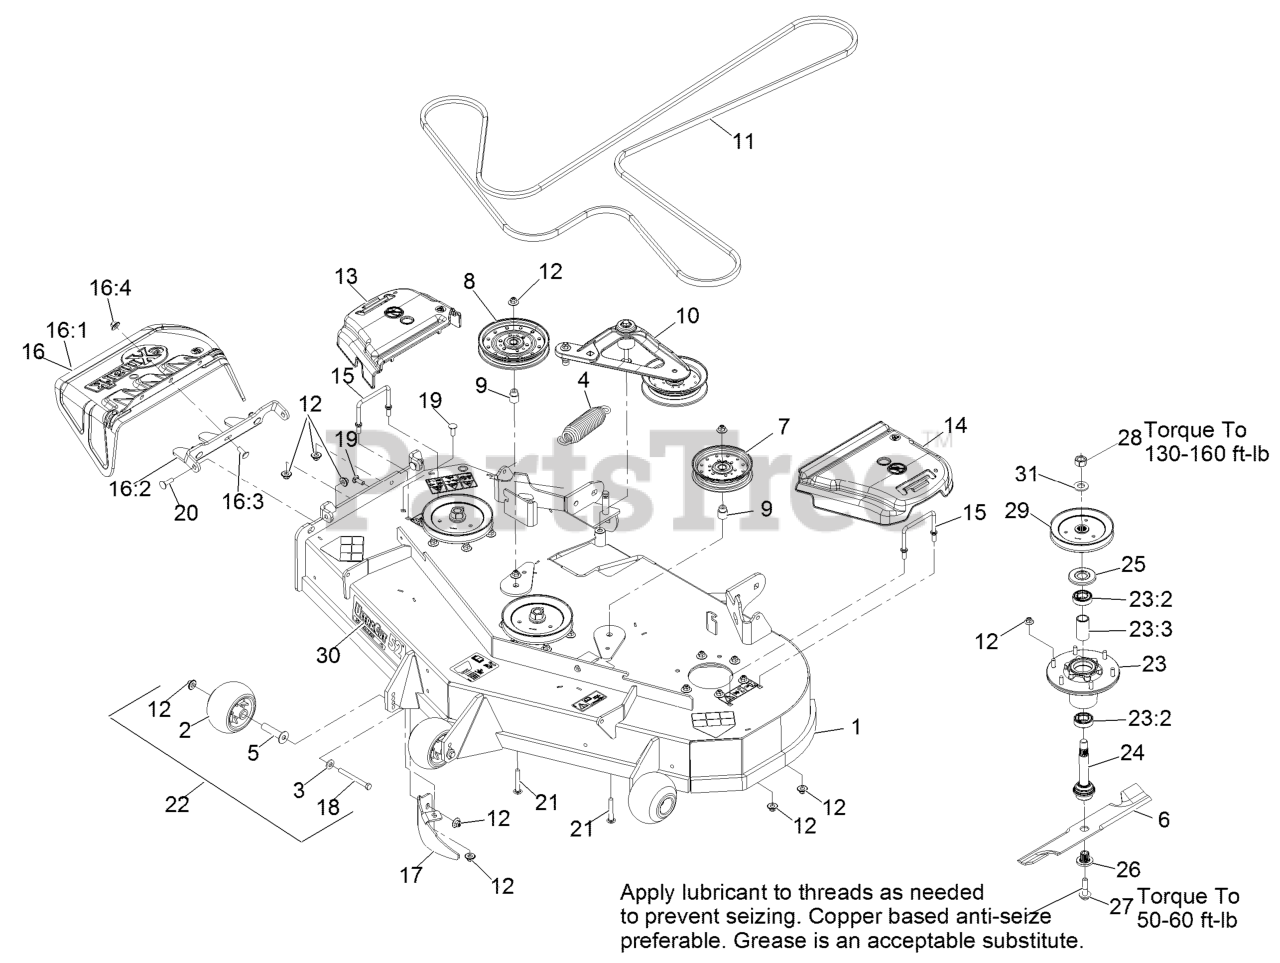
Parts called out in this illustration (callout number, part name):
1	ASM,DECK W/ DECALS 52
2	ROLLER-SCALP, ANTI
3	WASHER-BELLEVILLE
4	SPRING-EXTENSION
5	AXLE, ROLLER
9	BUSHING-IDLER
10	DECK IDLER ASM
11	BELT,V-B X 186.00"
12	Nut-Nyloc 3/8-16 Flg
13	COVER-BELT, RH
14	COVER-BELT, LH
15	WIREFORM-COVER
16	ASM,DISCHARGE CHUTE
16:1	CHUTE,DISCHARGE
16:2	BRACKET,DISCHARGE CHUTE
16:3	SCREW-CARR
16:4	Nut-Nyloc 3/8-16 Flg
17	BAFFLE-DOGLEG, LZ-VT52
18	SCREW-HH 3/8-16 X 3 3/4 GR 8
19	SCREW-CARR
20	Bolt-Carriage 3/8-16 X 1 1/4
21	SCREW-CARR
22	KIT, ANTI-SCALP ROLLER
23	ASM-CUTTER HSG WITH BEARINGS
23:2	BEARING-BALL
23:3	SPACER-BEARING
24	ASM-SPINDLE AND SEAL
25	GUARD,BEARING TOP .989
26	BUSHING,SPLINED
27	SCREW,SEMS 1/2-20 X 2.19
28	NUT-HEX
29	SHEAVE,BLADE DRIVE 6.50
30	DECAL,ULTRACUT 52 SERIES
